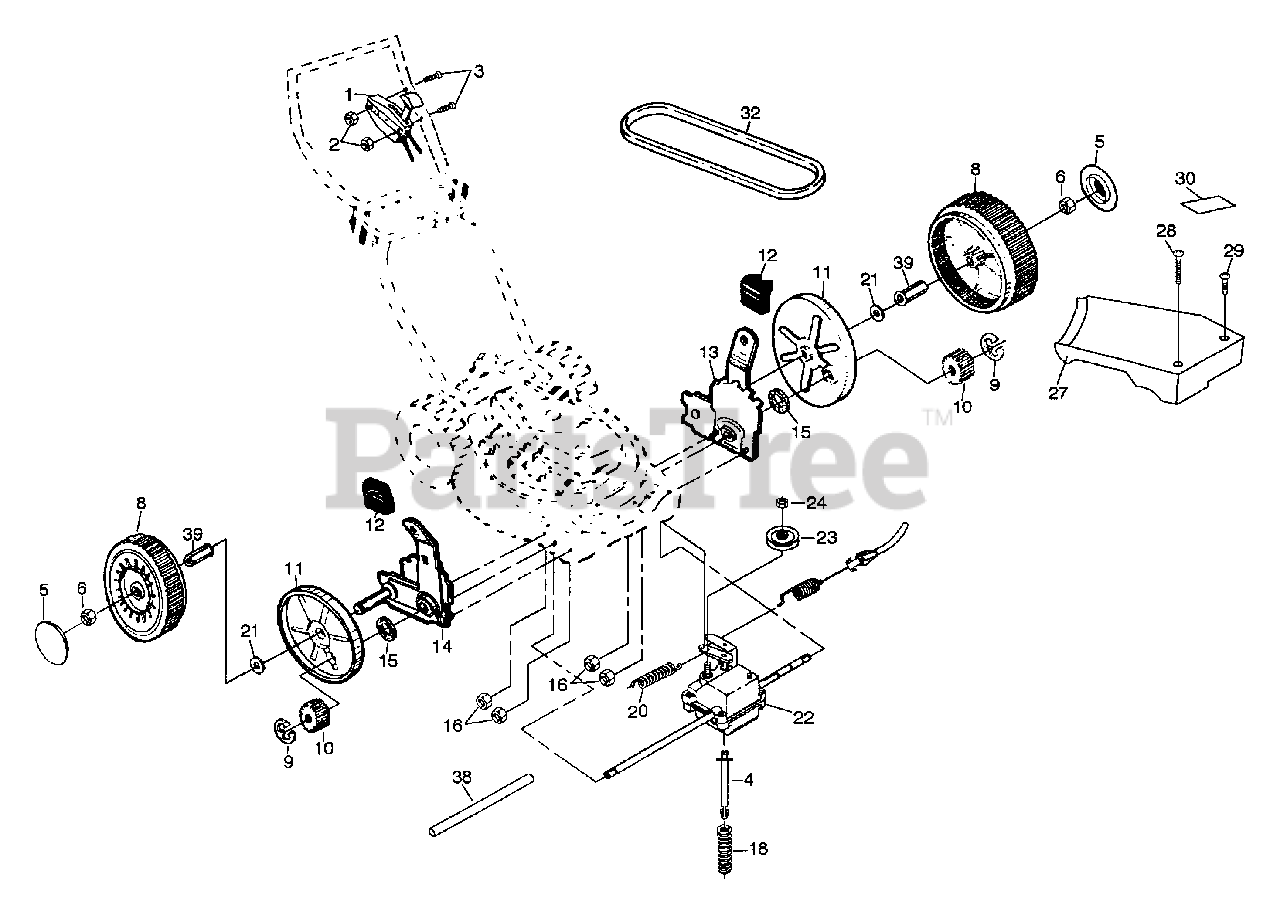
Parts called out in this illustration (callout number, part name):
1	Drive Control
2	Locknut #10-24
3	Hex Washer Head Screw 1/4-20 x 2.12
4	Spring Retainer
6	Nut
8	Wheel & Tire Assembly
11	Dust Cover
12	Selector Knob
13	Wheel Adjuster Assembly (Left)
14	Wheel Adjuster Assembly (Right)
16	Locknut
22	Gear Case Assembly
23	Drive Pulley
24	Locknut
27	Drive Cover
28	Pan Head Machine Screw #10-24 x 2-3/4
29	Pan Head Machine Screw #10-24 x 1-3/4
30	Drive Cover Decal
32	V-Belt
38	Drive Shaft Cover
